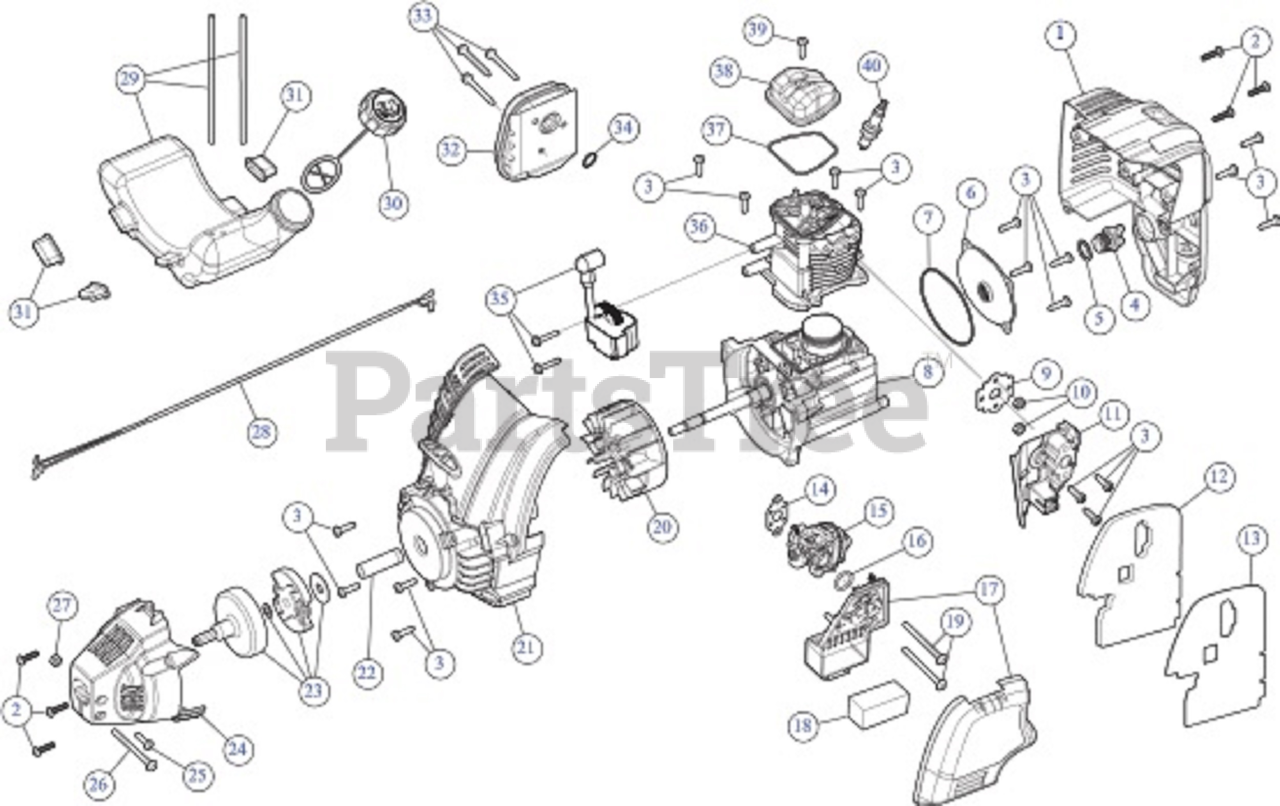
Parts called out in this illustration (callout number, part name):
1	Engine Cover Assembly
2	Cover Screw
4	Oil Plug
5	Oil Plug O-Ring
6	Crankcase Cover
7	Crankcase Cover O-Ring
8	Crankcase Assembly
9	Insulator Gasket
12	Heat Shield
15	Carburetor
17	Air Cleaner Cover Assembly
18	Air Filter
20	Flywheel Assembly
21	Starter Housing Assembly
22	Powershaft Spacer
23	Clutch Assembly
24	Clutch Cover
25	Anti-Rotation Screw
26	Clamp Screw
28	Lead Wires
29	Fuel Tank Assembly w/Fuel Lines
30	Fuel Tank Cap
31	Fuel Tank Pads
32	Muffler Assembly
33	Muffler Screw
34	Muffler Gasket
35	Module Assembly
36	Cylinder Assembly
37	Rocker Cover O-Ring
38	Rocker Cover
39	Rocker Cover Screw
40	Spark Plug
